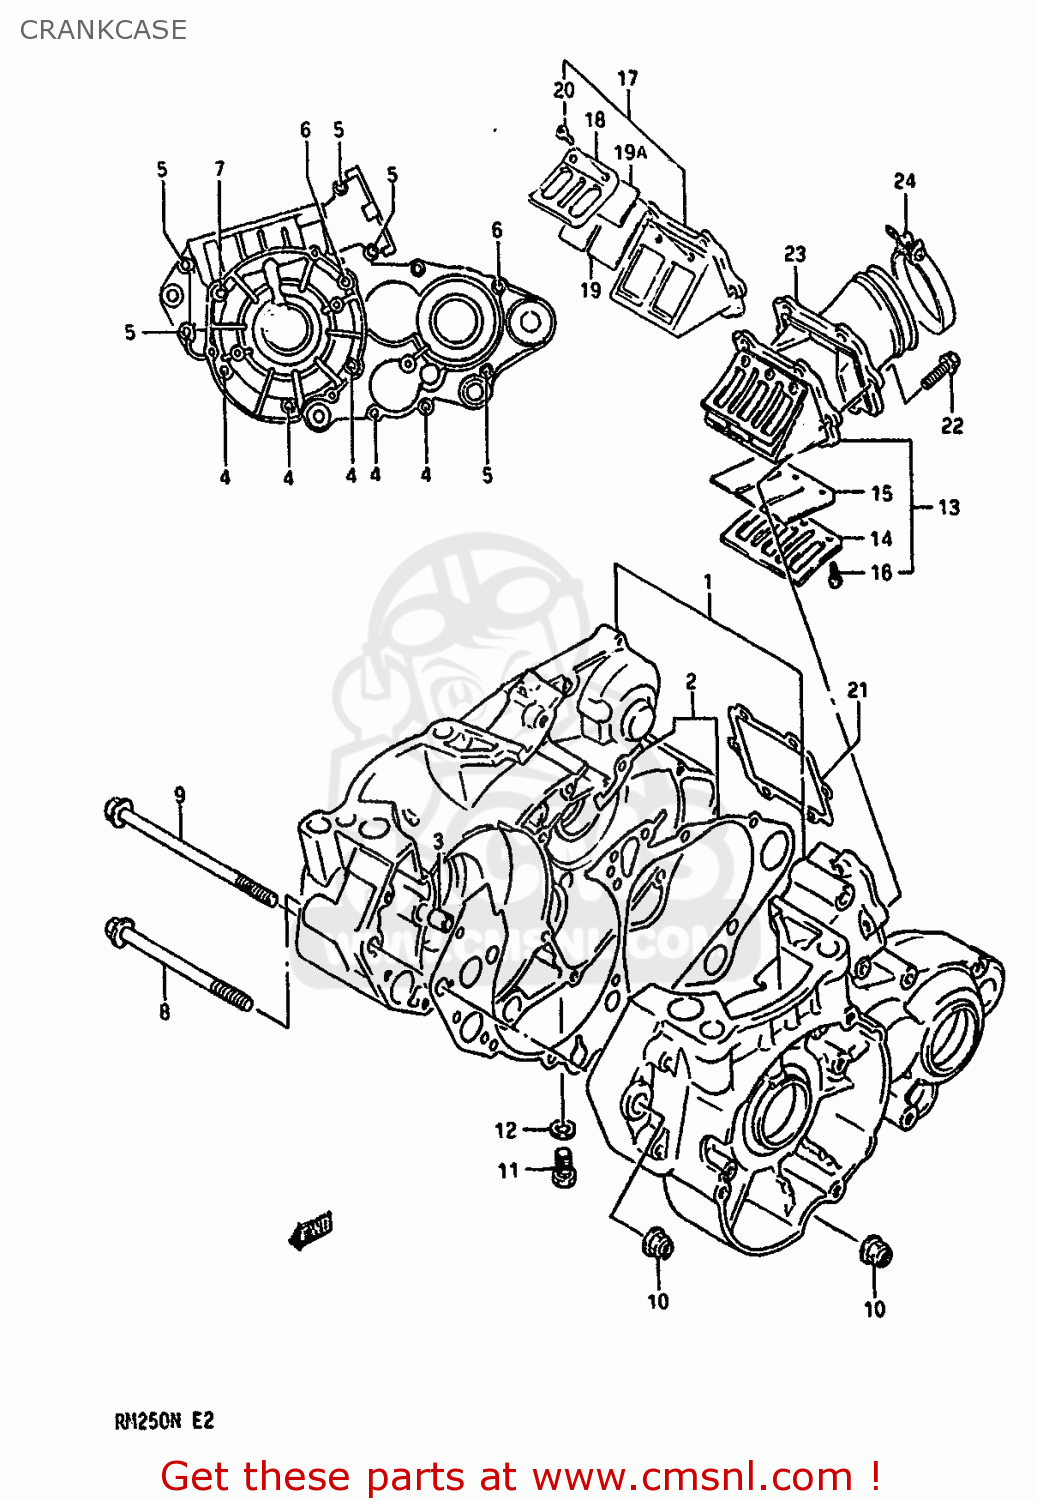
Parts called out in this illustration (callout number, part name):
1	CRANKCASE SET
2	GASKET,CRANKCASE (NAS)
3	PIN
4	BOLT
5	BOLT
6	BOLT
7	BOLT
8	BOLT
9	BOLT
10	NUT
11	BOLT,8X16
12	GASKET 8.2X14X1 (NAS)
13	VALVE ASSEMBLY,REED
14	STOPPER,REED VALVE
15	VALVE,REED
16	SCREW
17	VALVE ASSEMBLY,REED
18	STOPPER,REED VALVE
19	VALVE,REED
19A	VALVE,REED UPR
20	SCREW
21	GASKET,REED VALVE (NAS)
22	BOLT
23	PIPE,INTAKE
24	CLAMP
